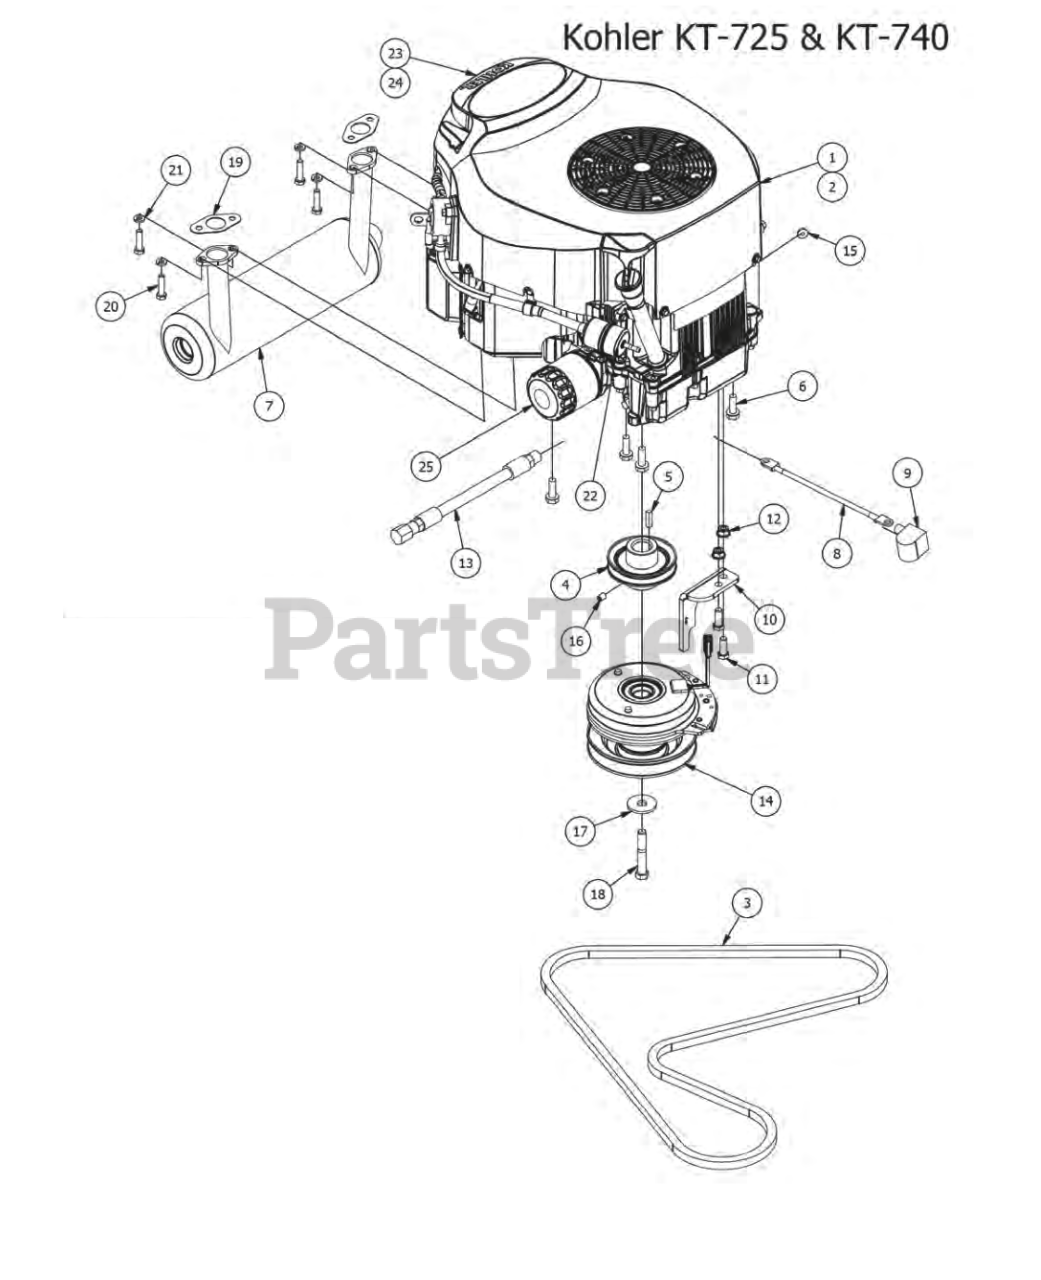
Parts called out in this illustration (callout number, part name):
1	Kohler KT-725 (48" Deck)
2	Kohler KT-740 (54" Deck)
4	3-3/4" Motor Pulley
5	1/4" x 1" Key
6	3/8 x 1 1/8 bolt
7	2014 MZ Muffler-725cc Kohler
8	Ground Cable
9	Black Boot For ground cable
10	Warner Clutch A-R Bracket
11	3/8" x 1" Hex Bolt
12	3/8" Nylock Flange Nut
13	Oil drain Hose
14	Clutch 2015 Magnum/MZ
15	1/4-20 Hex Flange Nuts Zinc w/Serrations
16	3/8" Set Screw
17	1/2 Belleville Washer
18	7/16" x 2 3/4" Fine Thread Bolt
19	Exhaust Gasket
20	5/16 x 1 1/4 Hex Bolt
21	5/16" Lock Washer
22	KT-725 & KT-740 Fuel Filter
23	KT-725 & KT-740 Precleaner
24	KT-725 & KT-740 Air Elemet
25	KT-725 & KT-740 Oil Filter
